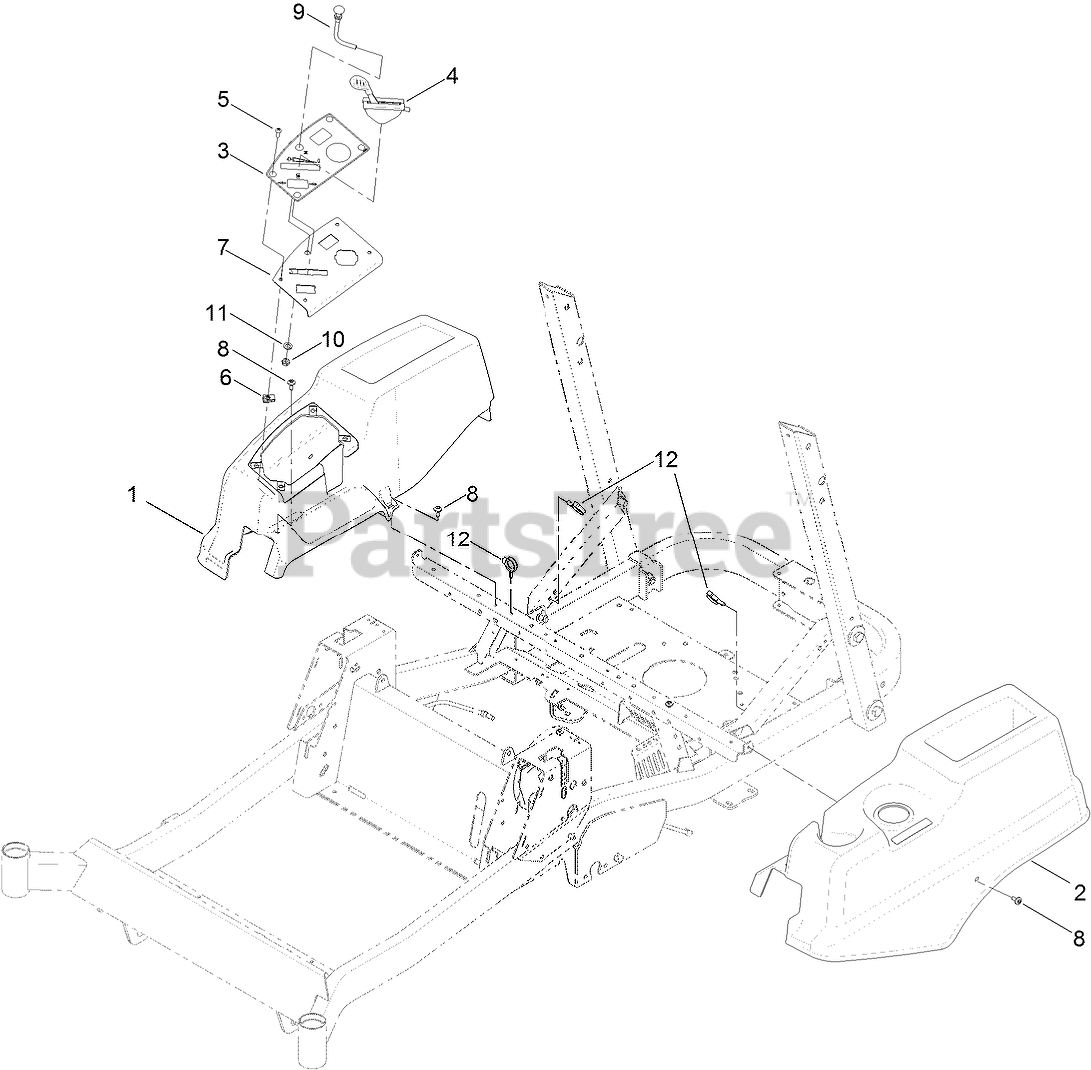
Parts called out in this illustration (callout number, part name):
1	POD-RH
2	POD-LH
3	DECAL-PANEL, CONTROL
4	CABLE-THROTTLE
5	SCREW-PRH
7	PANEL-CONTROL
8	SCREW-SHOULDER
9	CABLE-CHOKE
10	WASHER-LOCK
11	NUT-HJ
12	CLAMP-HOSE
